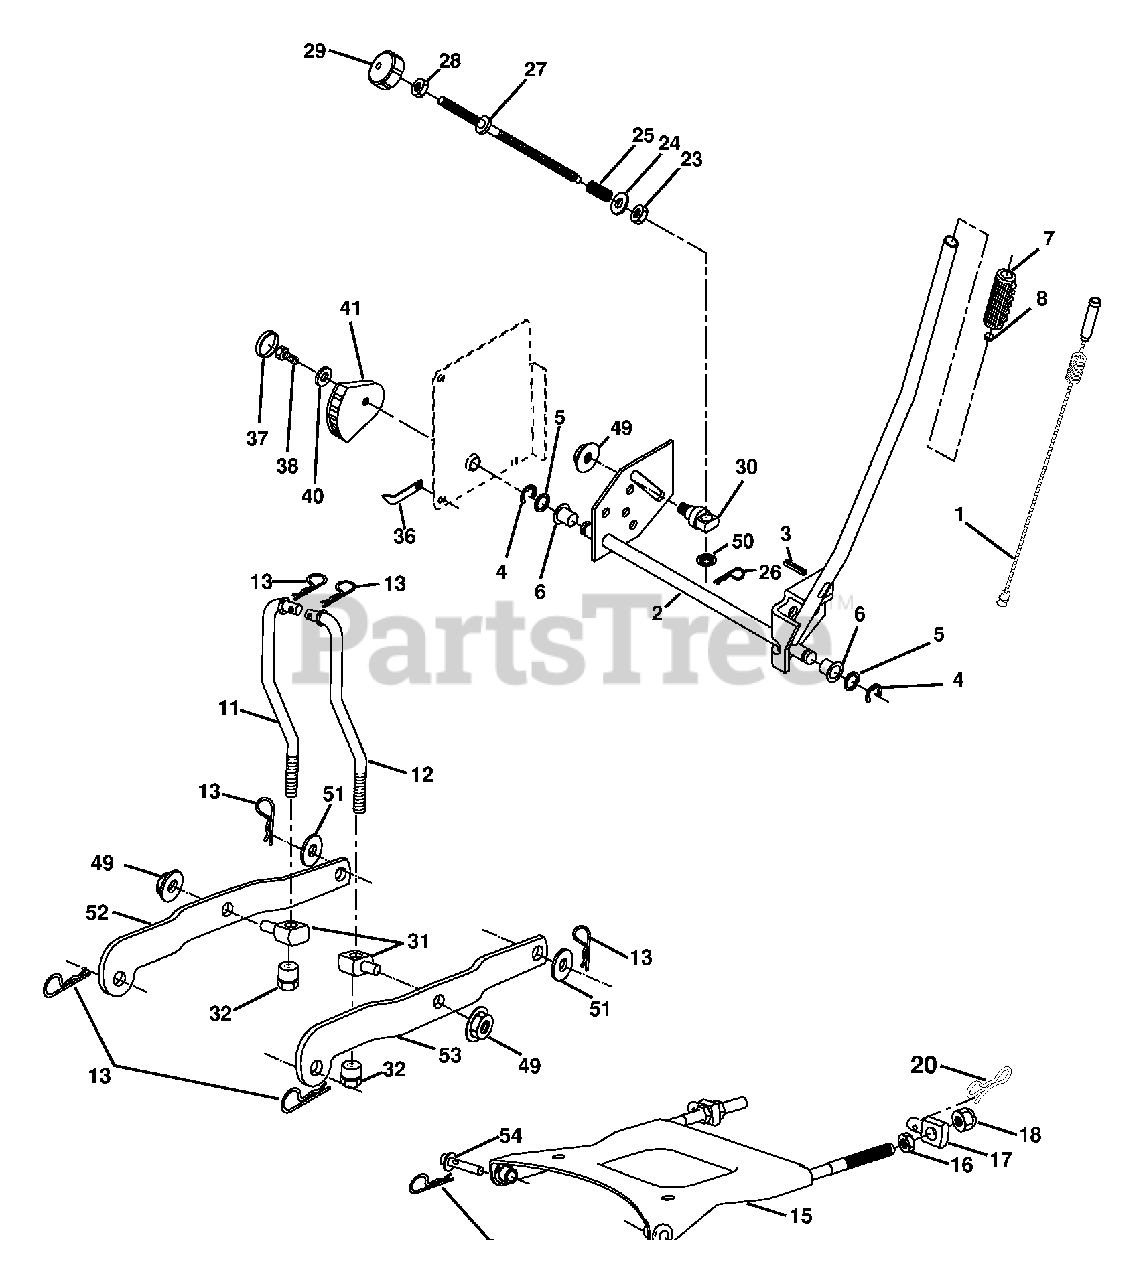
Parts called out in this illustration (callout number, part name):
1	Plunger Asm.
2	Shaft Asm Lift RH w/Inf
3	Pin Groove
4	E Ring #5133-62
5	Washer 21/32 x 1 x 21 Ga.
6	Bearing Nylon Blk 629 Id
7	Grip Handle
11	Link Lift LH
12	Link Lift RH
13	Retainer Spring
15	Plate Asm. Suspension Front
16	Nut Jam Hex 1/2-13 unc
17	Trunnion Front Susp.
18	Nut Lock w/Wsh 1/2-13 unc
20	Pin Cotter 7/16 Bow Tie Lock
23	Nut Special
24	Washer 13/32 x 5/8 x 16 Ga.
25	Spring Infin, Height
26	Retainer Clip
27	Rod Adjust Lift
28	Nut Hex Jam 3/8-16 unc
29	Knob Infin. Height
30	Trunnion Infin, Height
31	Trunnion Susp. Arm
32	Nut Lift Link 7/16-20
36	Pointer Height Ind.
37	Plug Hole
38	Screw 5/16-18 x 1
40	Washer 11/32 x 1-1/2 10 Ga.
41	Scale Indicator Height
49	Nut Hex Flange Lock
50	Nut Push
51	Washer 17/32 x 7/8 x 16 Ga.
52	Arm Susp. Rear LH
53	Arm Susp. Rear RH
54	Pin
